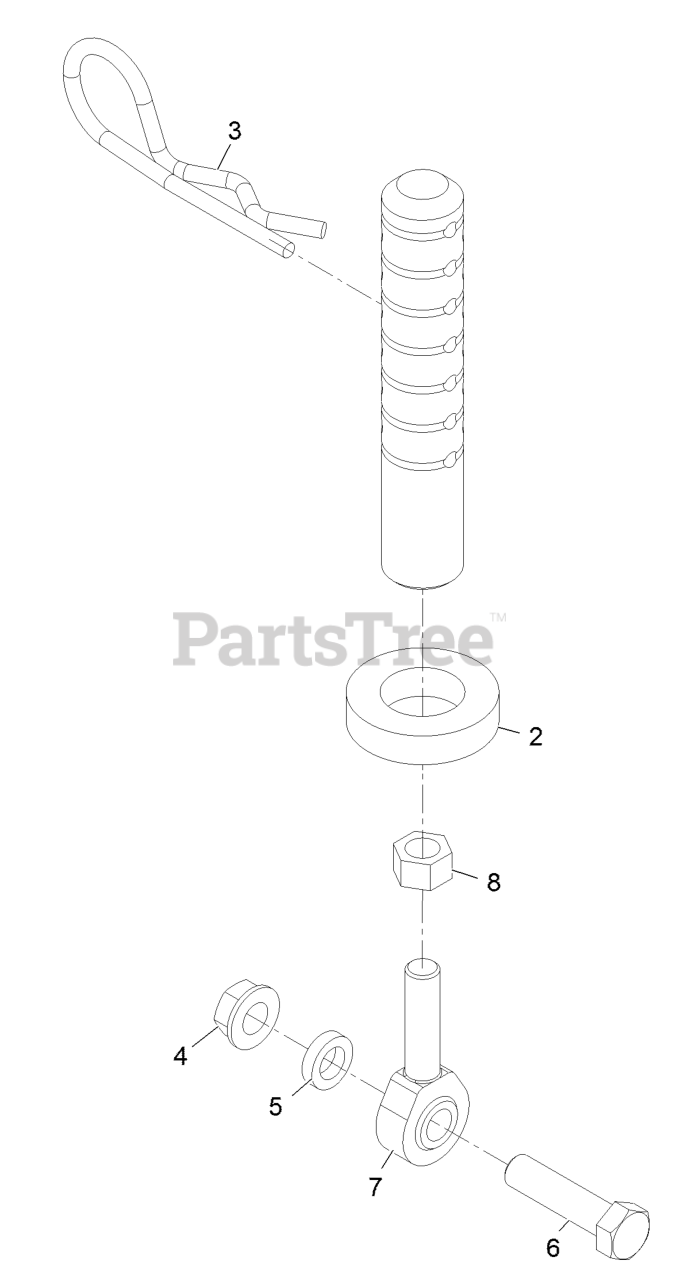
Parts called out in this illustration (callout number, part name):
2	SPACER-DECK SUPPORT
3	PIN-CUT HEIGHT
4	NUT-HHF, WHIZ
5	SPACER-IDLER
6	SCREW-HH
7	BALLJOINT
8	NUT-HJ
